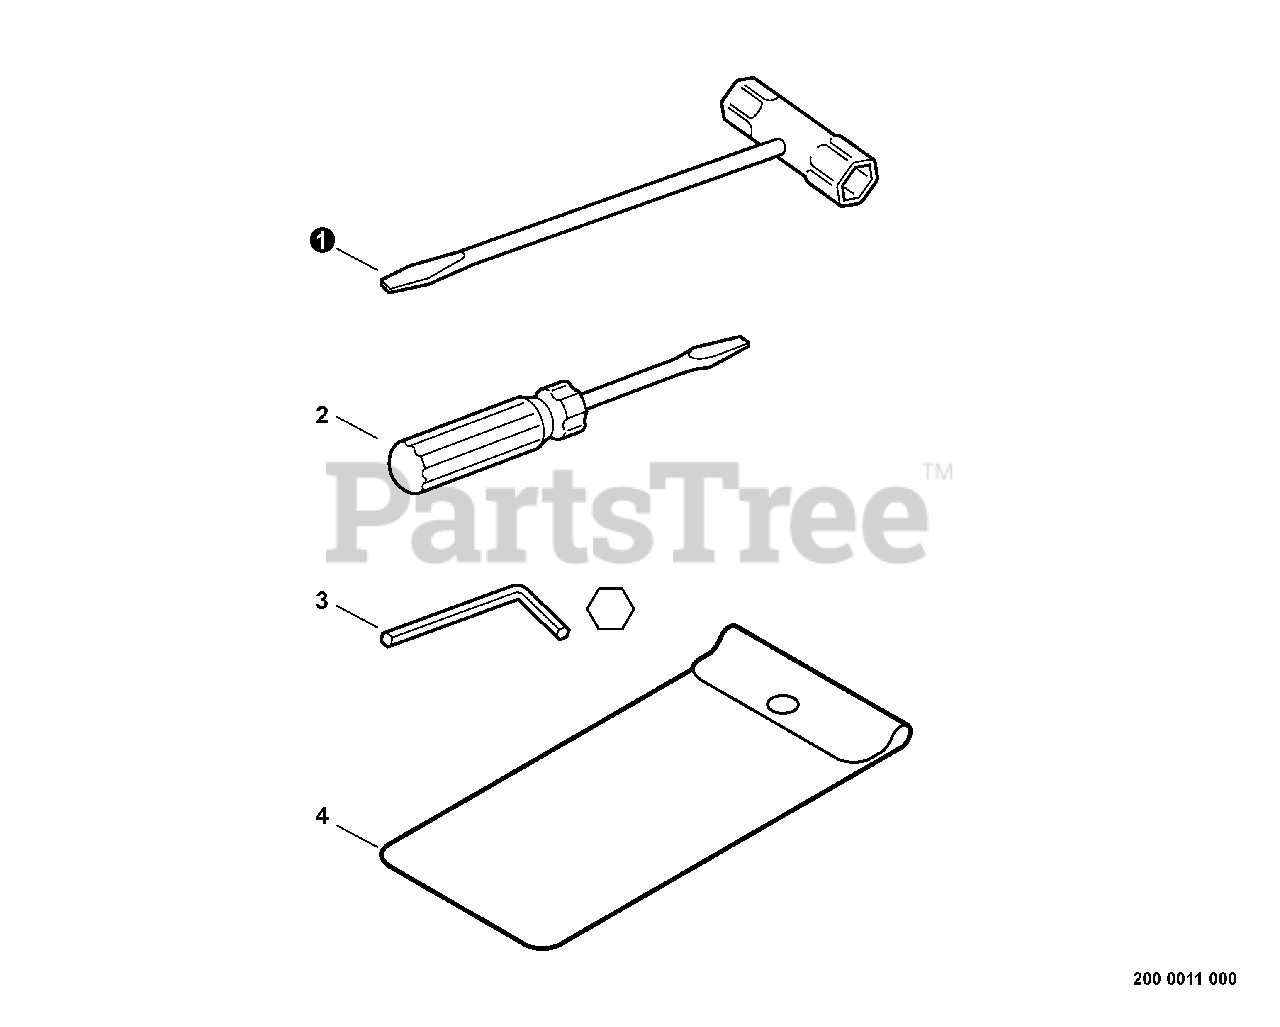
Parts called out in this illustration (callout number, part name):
1	T-WRENCH 13×19 L= 180
2	SCREWDRIVER, PHILLIPS
3	WRENCH, ALLEN
4	BAG, TOOL
